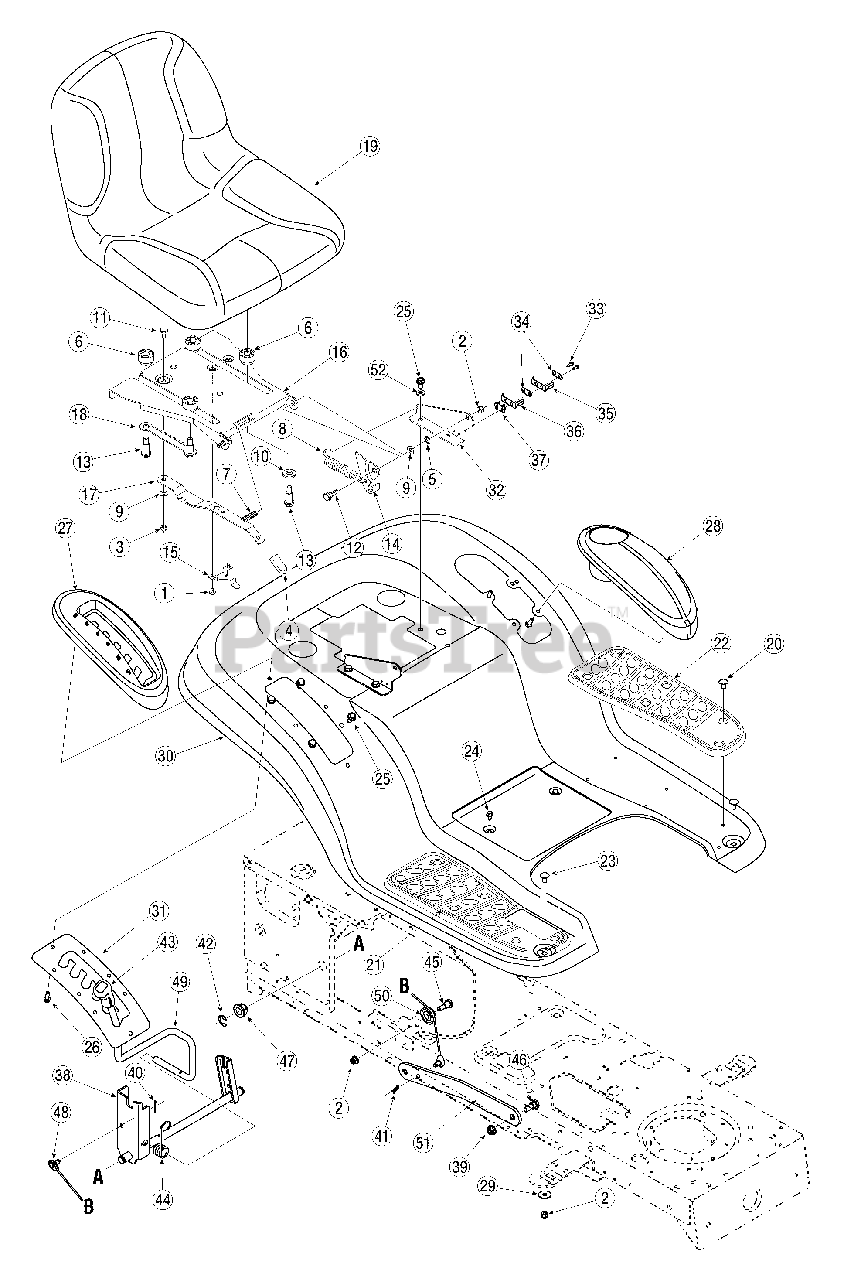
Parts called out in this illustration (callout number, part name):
1	Screw, #10-16 x.375
2	Nut, Flange Lock, 5/16-18, Gr F, Nylon
3	Nut, Flange Lock, 1/4-20
4	Seat Adjuster Grip
5	Nut, Speed,.3125 ID
6	Spacer
7	Compression Spring,.41 x 1.5
8	Spring, Extension,.84 Dia. x 4.6
9	Wash, Flat,.344 x.688 x.065
10	Wash, Flat,.531x 1.062 x.134
11	Screw, Shoulder,.340 x.285,1/4-20
12	Screw, Shoulder,.437 x.268, 5/16-18
13	Screw, Shoulder,.50 x.925, 3/8-16
14	Seat Bracket, Lift
15	Seat Stop
18	Seat Adjustment Selector
19	High Back Seat, Yellow
20	Ratchet Clip
21	RH Foot Pad, Rubber
22	LH Foot Pad, Rubber
23	Bolt, Carriage, 5/16-18,.62, Gr1
24	Screw, 1/4-20, 0.500
25	Screw, 5/16-12, 0.750
26	Screw, 1/4-15, 0.750
27	Cover, Lift Lever
28	Cover, w/ Cup Holder
29	Washer, Flat,.344 x 1.0 x.063
33	Screw, #8-18 x.50
34	Plate, Insulator
35	Spring Switch, Outer
36	Spring Switch, Inner
37	Plate, Insulator Boss
39	Nut, Flange Lock, 3/8-16, Gr F, Nylon
40	Pin, Cotter,.072 Dia. x 1.13
41	Pin, Cotter, 3/32, 1.0
42	Ring, E Type,.625 Dia.
43	Grip, Handle, 1/2
44	Spring, Torsion
45	Screw, 5/16-18 x.620 Gr2
46	Screw, Shld,.50 x.27, 3/8-16
47	Bearing, Hex Flange
48	Cable, Lift, 16.16
49	Handle, Lift
50	Pulley, Roller
52	Lock Washer, 5/16
